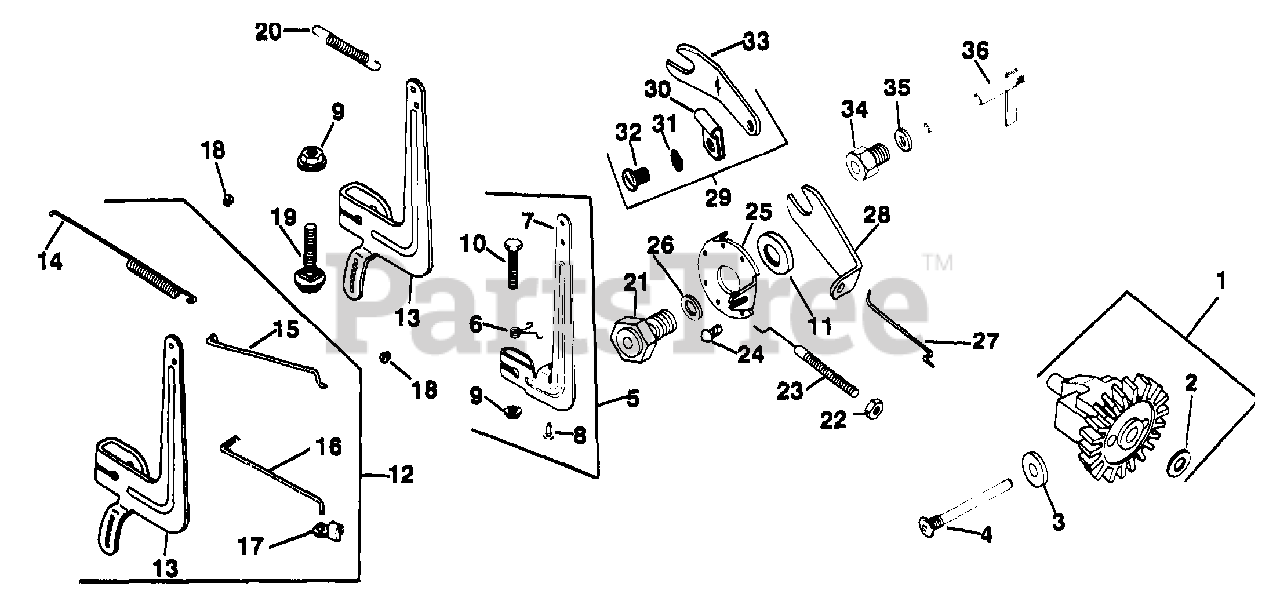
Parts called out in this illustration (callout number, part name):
1	KIT, GOVERNOR GEAR
17	BUSHING - USE 25 158 11
21	BUSHING - (#DSC)
22	NUT, MACH SCREW #8-32 GRD 2 USE 25 100 16-S
25	REGULATING DISC
36	KIT,SHAFT
